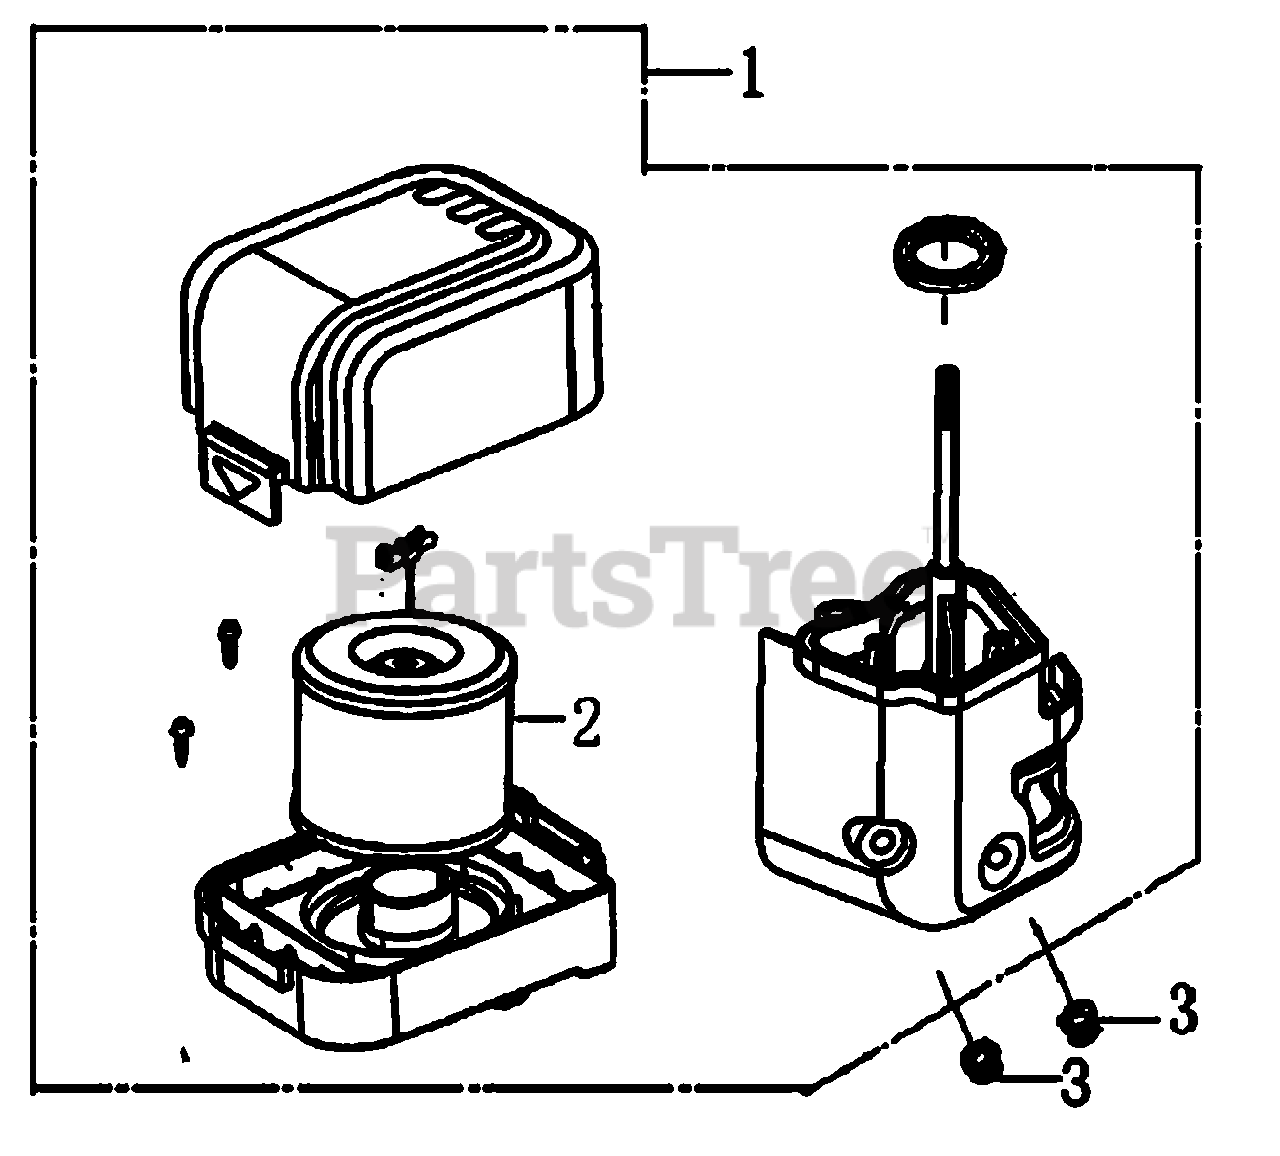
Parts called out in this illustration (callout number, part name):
1	AIR CLEANER ASSY
2	ELEMENT, AIR CLEANER
3	NUT, FLANGE 6MM
